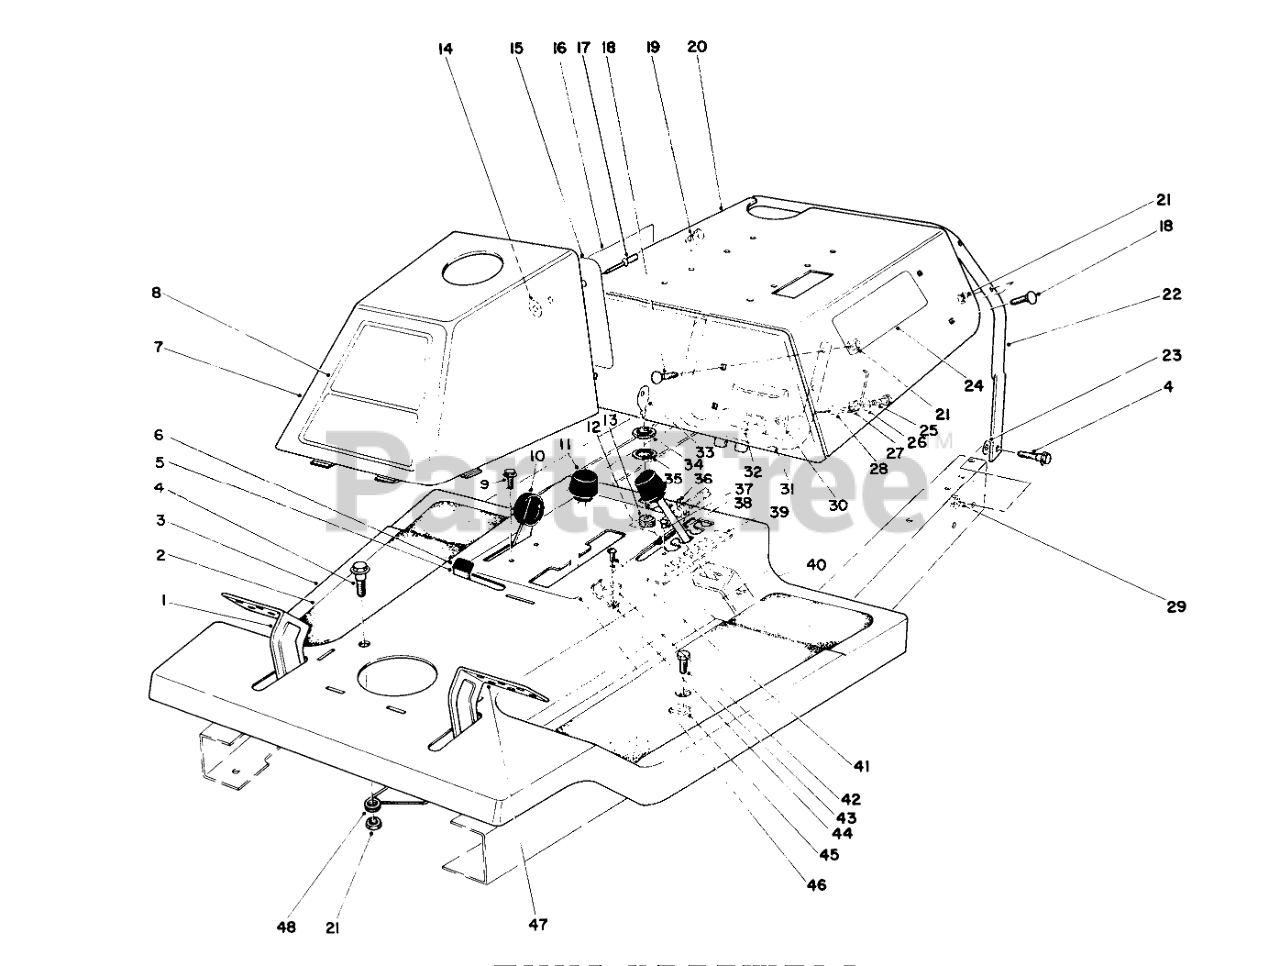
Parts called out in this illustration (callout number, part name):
1	Brake Pedal
2	TREAD-FOOT
3	Front Body Assembly (Incl. Ref. #37, 39, & 46)
4	SCREW-SHOULDER
5	Parking Brake
6	TIP-PARKING BRAKE
7	Tower (Incl. Ref. #14, 15, & 17)
8	725 DECAL
9	8X1/2 SELF TAP SCREW
10	THROTTLE CONTROL ASM
13	Switch-Starter (Incl. Ref. #33-35)
14	WASHER-PLAIN
15	Decal-Tower
16	Decal Shift Pattern
18	BOLT-CARR
19	CLIP-FUEL LINE
20	Body-Rear
21	NUT-LOCK, NI
22	Support-Rear Body
23	WASHER-PLAIN
24	Decal
25	SCREW-HH
26	WASHER-FLAT
27	Spring-Latch
28	LATCH SPACER
29	NUT-HF
30	Latch
31	Front Support
32	NUT-CAP
33	Key
34	NUT-HH
35	WASHER-TOOTH, INTERNAL
36	TIE-CABLE
37	RIVET-POP
38	Height of Cut Lever
39	Height Adjustment Plate
40	PIN-ROLL
42	WIRE CLAMP
43	SCREW-HH
44	NUT-KEPS
45	NUT-TINNERMAN
46	DECAL
47	Clutch Pedal
48	SPRING-PARKING BRAKE
